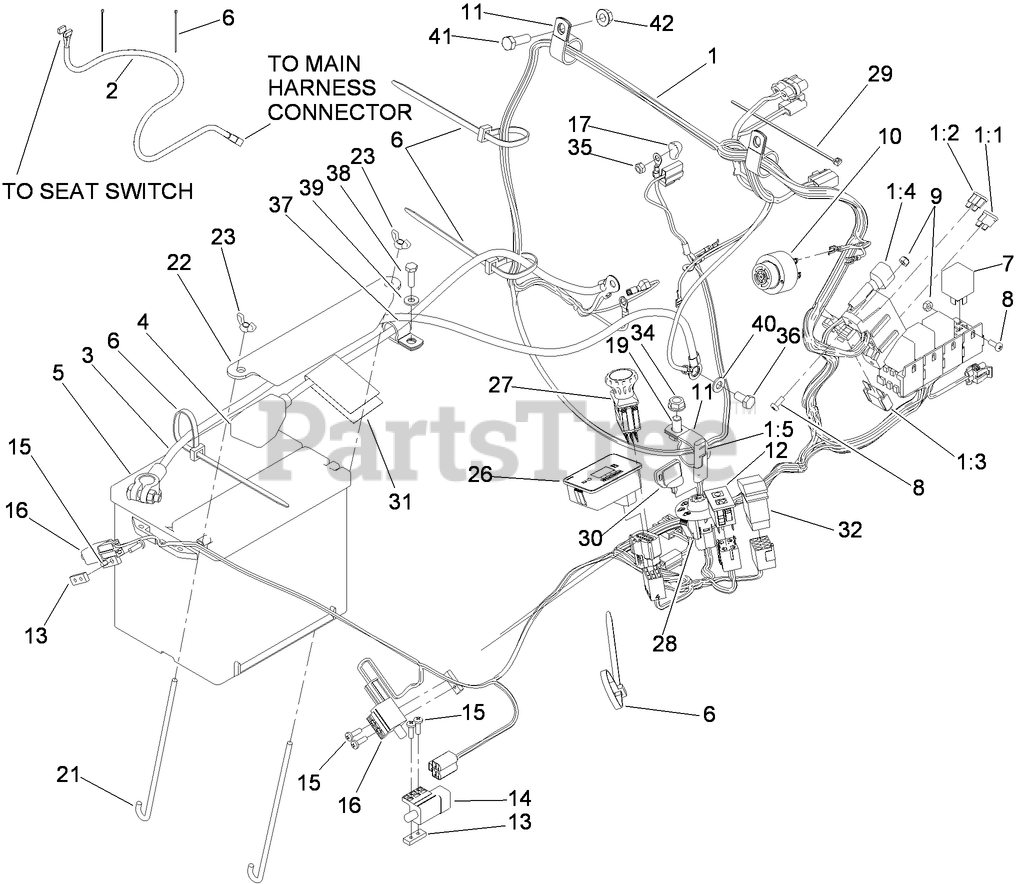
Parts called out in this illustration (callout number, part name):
1	HARNESS-WIRE
1:1	FUSE-BLADE, 10 AMP
1:2	FUSE-BLADE, 30 AMP
1:3	FUSE-BLADE, 50 AMP
1:5	CAP-PLUG
2	HARNESS-WIRING, SEAT
3	CABLE-BATTERY, NEGATIVE
4	CABLE-BATTERY, POSITIVE
5	BATTERY-DRY
6	TIE-PLASTIC
9	NUT-LOCK, NI
10	ALARM-TONE, DUAL
11	CLIP-LOOM
12	LAMP-WARNING
13	PLATE-TAPPED
14	SWITCH
15	SCREW-PPH
16	SWITCH-OPEN, NORMALLY
17	CAP-INSULATOR, RED
19	SCREW-HH
21	Bolt-Holddown
22	HOLDDOWN-BATTERY
23	WINGNUT
26	HOUR METER ASM
27	SWITCH-PTO, 10 AMP
28	SWITCH-IGNITION
29	TIE-CABLE
30	KEY-IGNITION
31	DECAL-INSTRUCTIONS, CHARGING
32	SWITCH-ROCKER
34	NUT-HHF, WHIZ
35	NUT-LOCK
36	SCREW-HH
37	CLIP-LOOM
38	SCREW-HH
39	WASHER-FLAT
40	WASHER-PLAIN
41	SCREW-HH
42	NUT-HF
